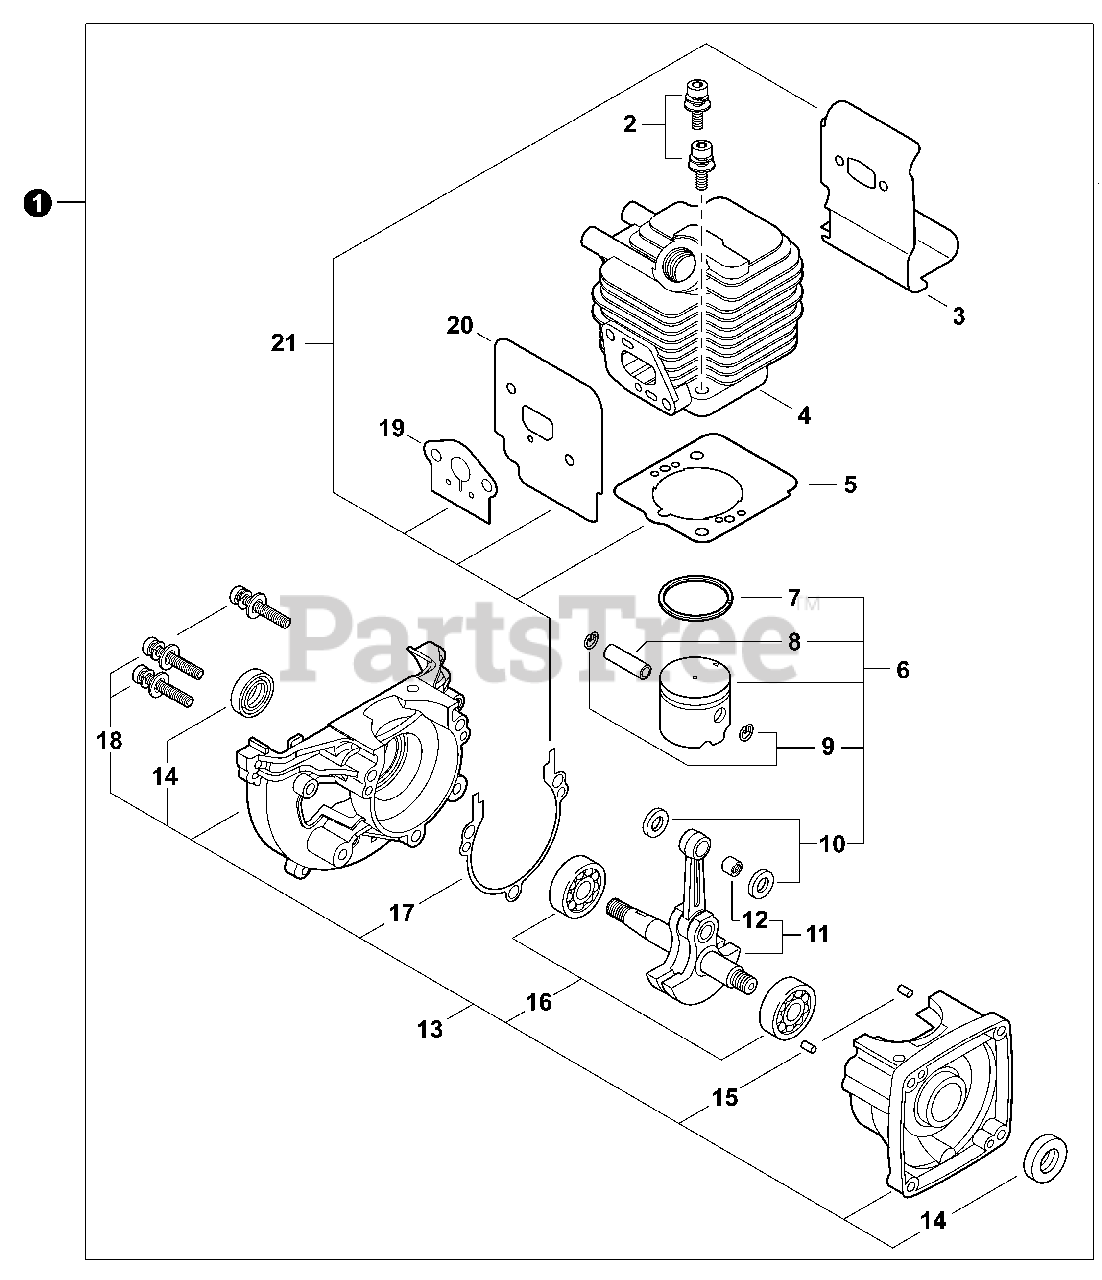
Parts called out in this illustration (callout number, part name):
1	SHORT BLOCK
2	BOLT 5x22
3	HEAT SHIELD, EXHAUST
4	CYLINDER
5	GASKET, CYLINDER
6	PISTON KIT
7	RING, PISTON
8	PIN, PISTON 8
9	RING, SNAP
10	WASHER, THRUST
11	CRANKSHAFT ASSY
12	BEARING, NEEDLE 8
13	CRANKCASE KIT
14	SEAL, OIL 12
15	PIN, LOCATING 4x8
16	BEARING, BALL
17	GASKET, CRANKCASE
18	BOLT 5x28
19	GASKET, INTAKE
20	HEAT SHIELD, INTAKE
21	GASKET KIT: ENGINE, INTAKE, EXHAUST
